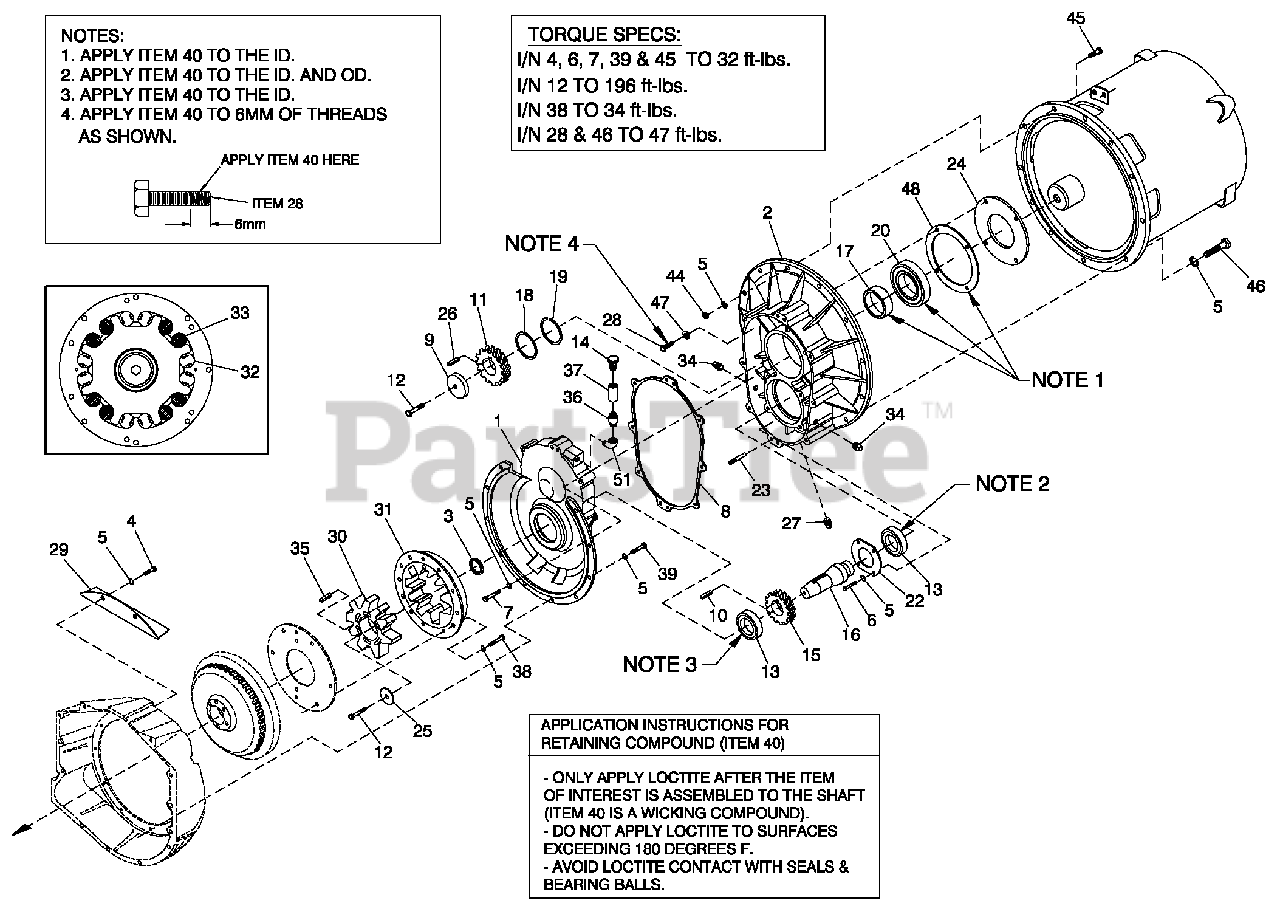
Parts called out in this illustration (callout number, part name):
1	GEAR CASE ENG. MACHINED
2	GEAR CASE ALT. MACHINED
3	SEALOIL
4	SCREW HHC M10-1.5X 20 G8.8
5	WASHER LOCK M10
6	SCREW HHC M10-1.5X 25 G8.8
7	SCREW HHC M10-1.5X 70 G8.8
8	GASKET 390 GEAR BOX
9	SPACER .69 X 2.75 X .37 ST/ZNC
10	KEY 10 X 16 X 46
11	GEAR OUTPUT 1.65:1
12	SCREW HHC M16-2.0 X 35 G10.9
13	BALLBRG 65 X 120 X 23
14	BREATHER
15	GEAR INPUT 1.65:1
16	SHAFT 390 INPUT GEAR
17	COLLAR HARDENED
18	SEALOIL
19	SNAP RING INT 120MM
20	BEARING #6213 SEALED
22	PLATE INTRNLBRG RET
23	PIN DOWEL M8 X 24
24	PLATE BEARING THRST
25	SPACER STRESSPROOF
26	KEY 10 X 16 X 40
27	PLUG PIPE 3/8"MAGNETIC
28	SCREW HHFC M10-1.5X 25 G10.9
29	COVER GEARBOX GUARD
30	COUPLING INNER DRAWN
31	COUPLING OUTER MACHN
32	DAMPER GB CPLR VIBRA
33	DAMPER GB CPLR VIBRA
34	PLUG STD PIPE 3/8 STEEL SQ HD
35	KEY 10 X 16 X 50
36	NIPPLE PIPE3/8NPTX 3-1/2
37	COUPLING FULL 3/8-18
38	SCREW HHC 3/8-16 X 1-1/2G8
39	SCREW HHC M10-1.5X 25 G8.8
40	RETAINING COMPOUND
44	NUT HEX M10-1.5 G8 YEL CHR
45	SCREW HHC M10-1.5 X 60 G8.8
46	SCREW HHC M10-1.5 X 40 G10.9
47	WASHER FLAT M10 SEALING COPPER
48	GASKET SEAL PLATE 390 GB
50	THREADLOCK AND SEALANT
51	ELBOW 90D STREET3/8
